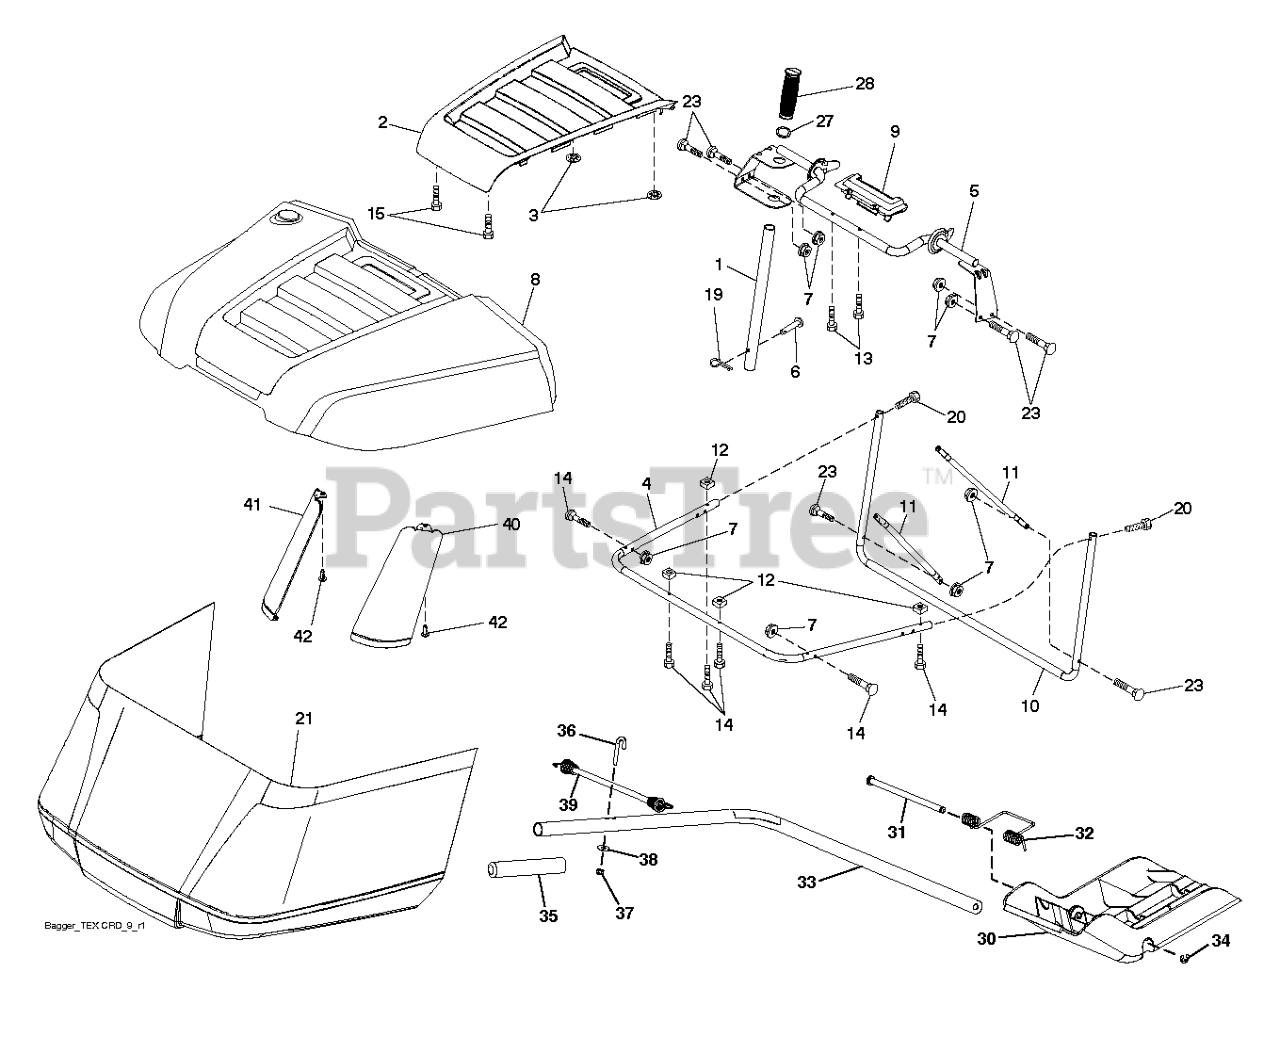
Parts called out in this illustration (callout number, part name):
1	TUBE.HANDLE.BAGGER.CRD/SRD.BLA
2	APPLIQUE.TOP.BAG.SRD.ORANGE
3	NUT.PUSH.156
4	SUBASM.TOP.TUBE.TEX.CRD
5	FRAME.ASM.TOP.BAGGER.SRD
6	RIVET,DRILLED
7	NUT T
8	BAGGER.TOP.SUB.ASSEM.SRD
9	INSERT.HANDLE.BAGGER.(2 2)
10	FRAME FRAME.FRONT.TEX.CRD
11	BRACE BRACE SIDE TUBE
12	NUT.SQUARE.1/4
13	SCREW.1/4X1.150.HXWSH
14	BOLT.SHOULDER.HX.WSH.1/4X1.150
15	SCREW,#8.FLAT.HEAD.DRILL.TIP
19	PIN.COTTER.5/16.BOW TI
20	SCREW.HEXCAP.1/4-20X1.375(2 2)
21	BAGGER.TOP.SRD.APPLIQUE
27	RB GROMMET.RUBBER.SRD
28	GRIP.HANDLE.BLACK
30	PLUG PLUG
31	PIN PIN.HINGE
32	SPRING SPRING DOUBLE TORSION
33	SHAFT SHAFT TEX CRD MULCH PLU
34	E-RING.5/16"
35	GRIP GRIP MULCH PLUG HAND
36	BOLT BOLT J
39	BUBGEE BUBGEE TEX CRD
42	CLIP CHRISTMAS TREE CLIP
